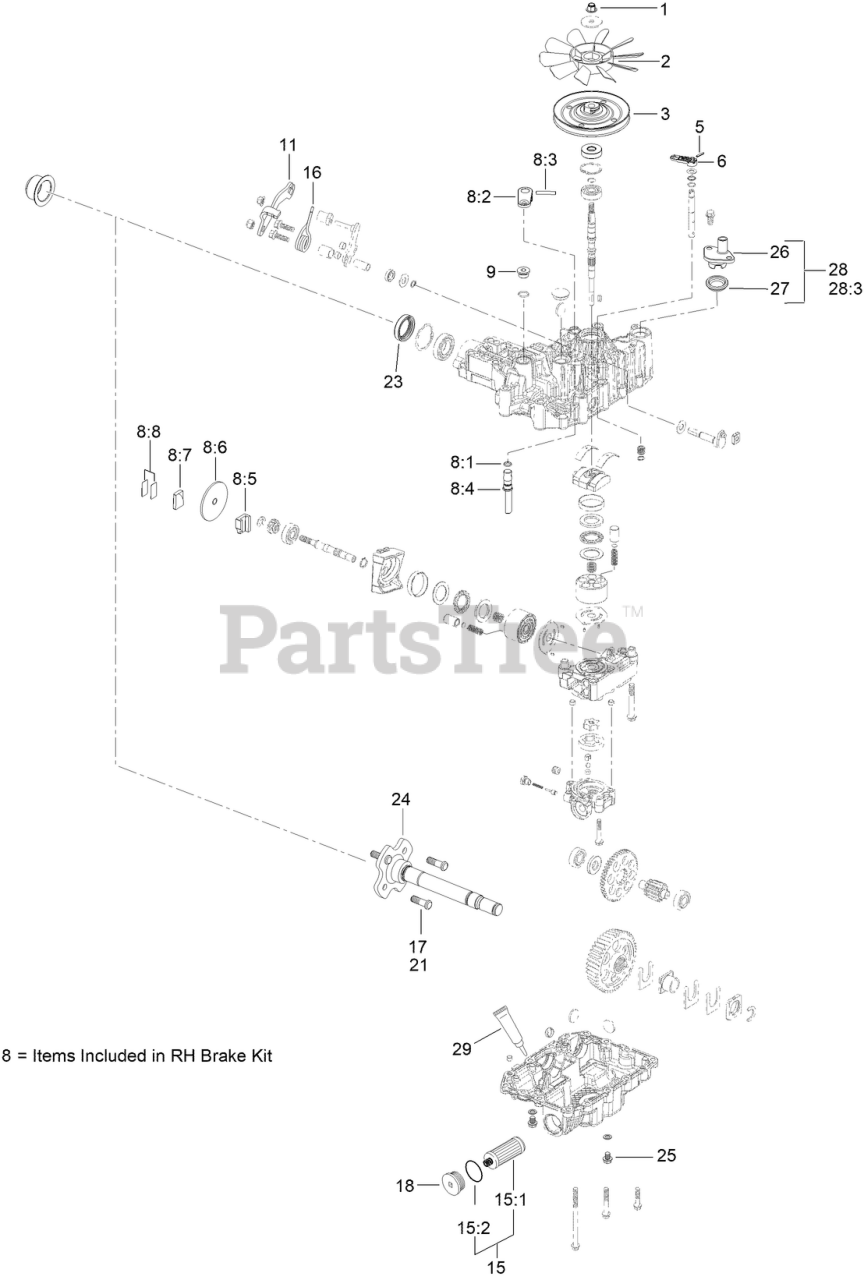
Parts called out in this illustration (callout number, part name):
1	NUT-LOCK
3	PULLEY
6	LEVER-BYPASS
8	BRAKE KIT,LEFT
8:1	O-RING
8:2	ARM-BRAKE
8:3	Pin-Roll
8:4	SHAFT-BRAKE
8:5	ACTUATOR-BRAKE
8:6	DISC-BRAKE
8:7	SHOE-BRAKE
8:8	SHIM KIT
9	CAP-OIL
11	LEVER-CONTROL, RH
15	HYDRO FILTER KIT
15:1	FILTER
15:2	O-RING
16	SPRING-TORSION
17	STUD-WHEEL
18	CAP-OIL FILTER
21	STUD-WHEEL
23	SEAL-AXLE, UA
25	DRAIN BOLT
26	EXPANSION FITTING
27	GROMMET SEAL, EXPANSION FITTING
28	EXPANSION FITTING - W/ SEAL
28:3	M8*20 FLANGE BOLT
29	SEAL KIT
